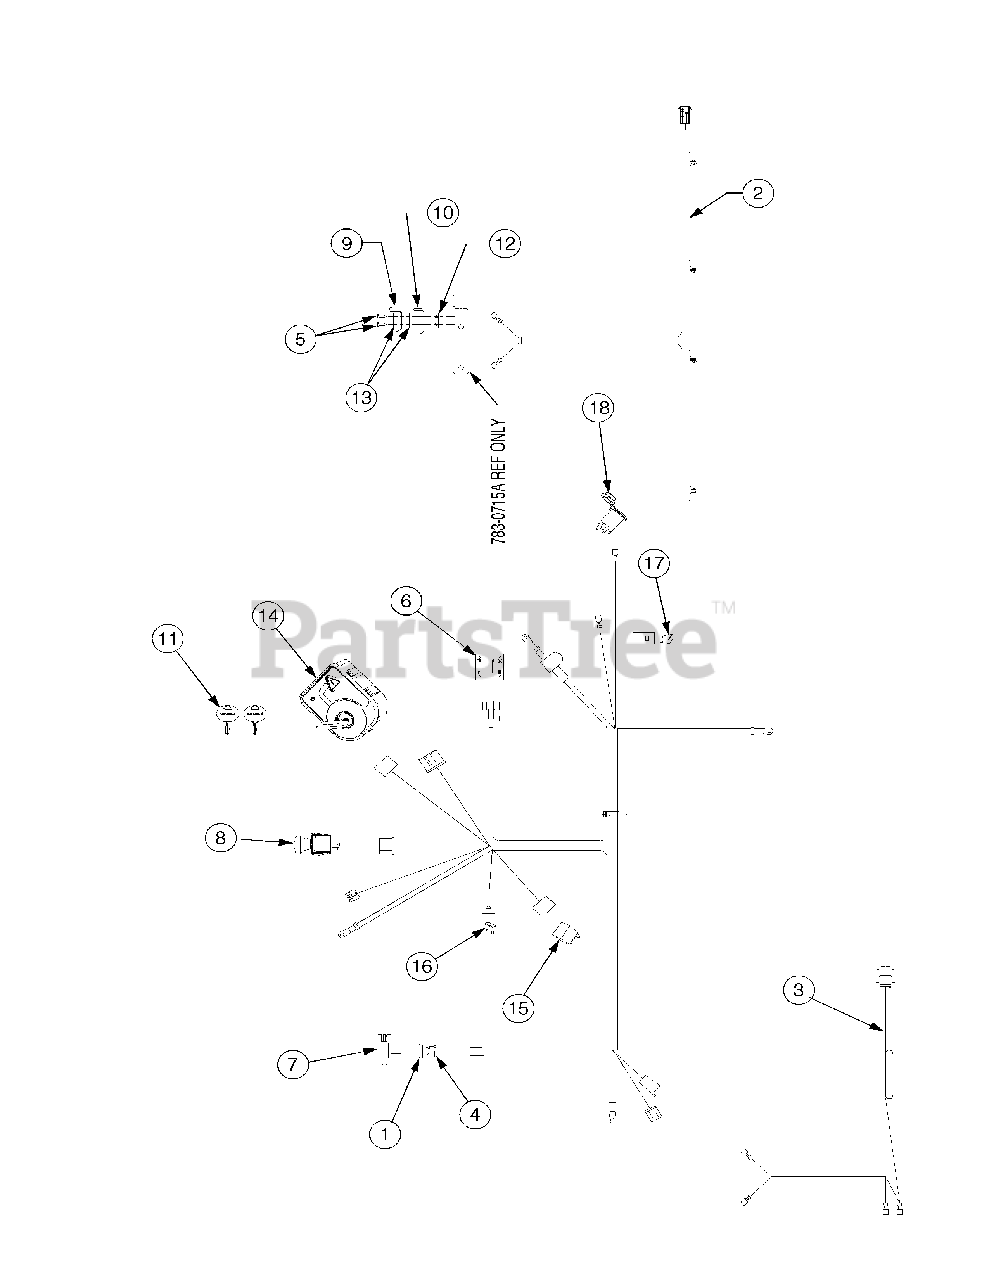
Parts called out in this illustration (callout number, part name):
1	Plate, Switch
2	Harness Assembly
3	Harness Assembly, Headlight
4	Screw, Hx. Wash. Hd. Tapp, 10-16 x .5
5	Screw, Hx. Wash. Hd. Tapp, 8-18 x .5
6	Indicator/ Meter Hour
7	Switch, Interlock
8	Switch, Electric PTO, Yellow Knob
9	Switch, Outer Seat Spring
10	Switch, Inner Seat Spring
11	Key, Switch, Plastic
12	Plate, Insulator Boss
13	Plate, Insulator
14	Switch, Key/Module
15	Relay
16	Fuse, 20 Amp
17	Fuse, 5 Amp
18	Receptacle, Power 12V
